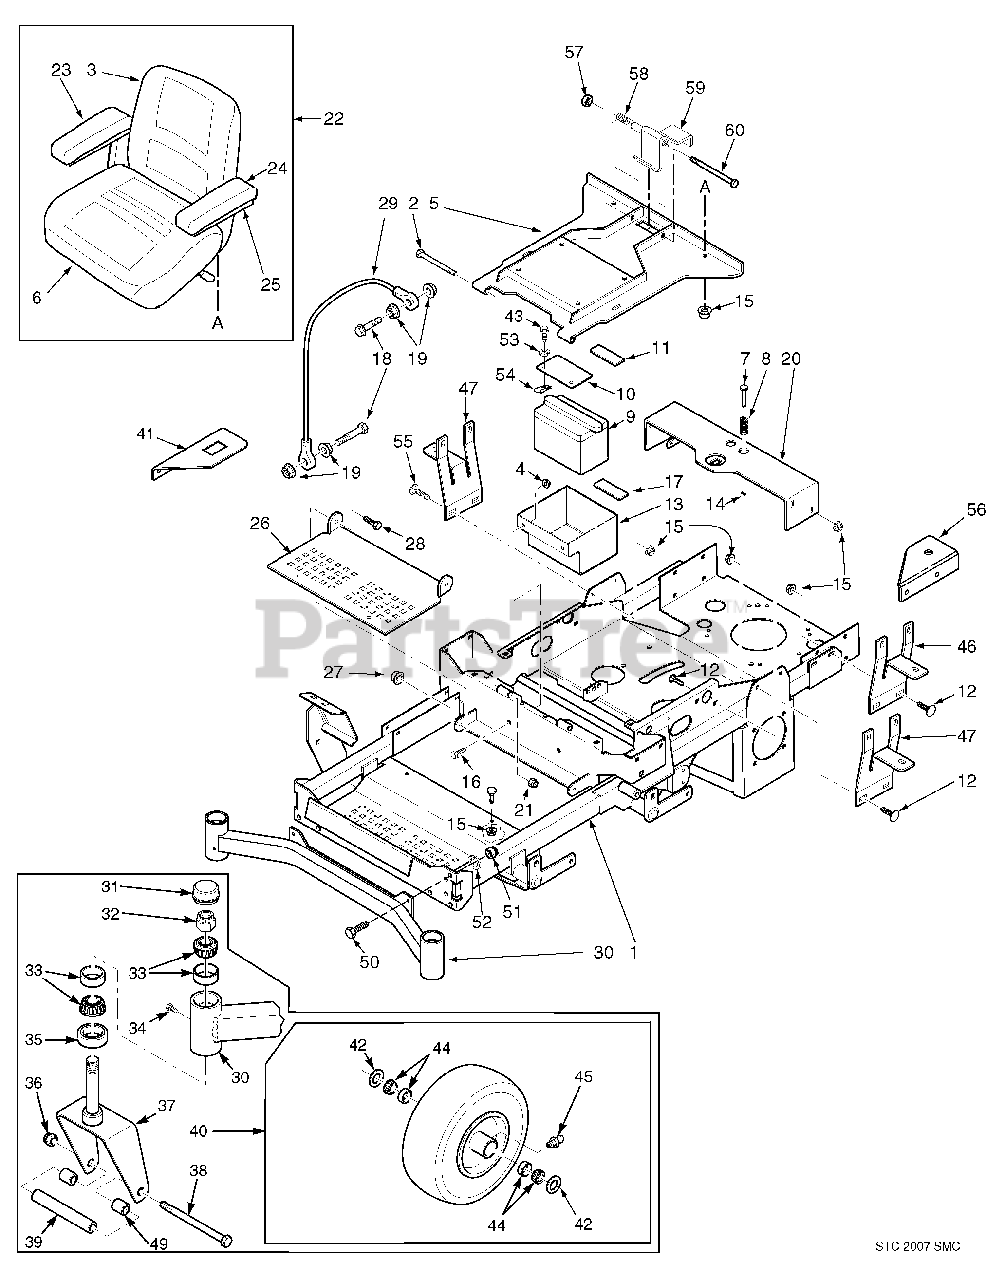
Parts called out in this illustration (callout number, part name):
1	Main Frame Assembly w/decals
2	Bolt, Hex Head 5/16-18 x 3-3/4"
3	Cushion, Back
4	Nut, Serr. Flange 3/8-16
5	Plate, Seat Mounting w/decals
6	Cushion, Lower Seat
7	Pin Retainer, Spring
8	Spring
9	Battery
10	Battery Cover
11	Battery Hold Down Pad
12	Bolt, Carr. 5/16-18 x 3/4"
13	Battery Box
14	Roll Pin, Spring 5/32 x 3/4"
15	Nut, Serr. Flange 5/16-18
16	Bolt, Hex Head 3/8-16 x 1"
17	Pad, Rubber
18	Bolt, Hex Head 1/4-20 x 1-1/4"
19	Nut, Serr. Flange 1/4-20
20	Seat Base Support
21	Nut, Elastic Stop 5/16-18
22	Seat Assembly w/ adj. rails
23	Arm Pad, RH
24	Arm Pad, LH
25	Channel, Armrest
26	Footplate
27	Nut, Elastic Stop 3/8-16
28	Bolt, Hex Head 3/8-16 x 1"
29	Cable, Seat Stop
30	Weldment, Caster Support
31	Cap, Grease
32	Nut, Elastic Stop 1.0-14
33	Bearing Set
34	Plug, 1/4-28
35	Seal, 2.0" OD x 1.625" ID
36	Nut, Elastic Stop 1/2-13
37	Yoke, Front Caster Wheel
38	Bolt, Hex Head 1/2-13 x 7-1/2"
39	Sleeve
40	Caster Wheel Assembly
41	Bracket, Hour Meter
43	Bolt, Hex Head 3/8-16 x 1-1/4"
44	Roller Bearing
45	Fitting, Grease
46	Mounting Bracket, Oil Tank
47	Mounting Bracket, Fuel Tank
48	Seat Pan
49	Spacer, Caster Wheel
50	Bolt, Hex Head 7/16-14 x 1-1/4"
51	Nut, Elastic Stop 7/16-14
52	Lockwasher, 7/16
53	Lock Washer. 3/8 Spring
54	U-Nut, 3/8-16
55	Bolt, Carriage 5/16-18 x 1"
56	Bracket, Fuel Valve
57	Lock Nut, 3/8-16 Center Lock
58	Spring, Seat Latch
59	Seat Latch Weldment
60	Bolt, Hex Head 3/8-16 x 6"
